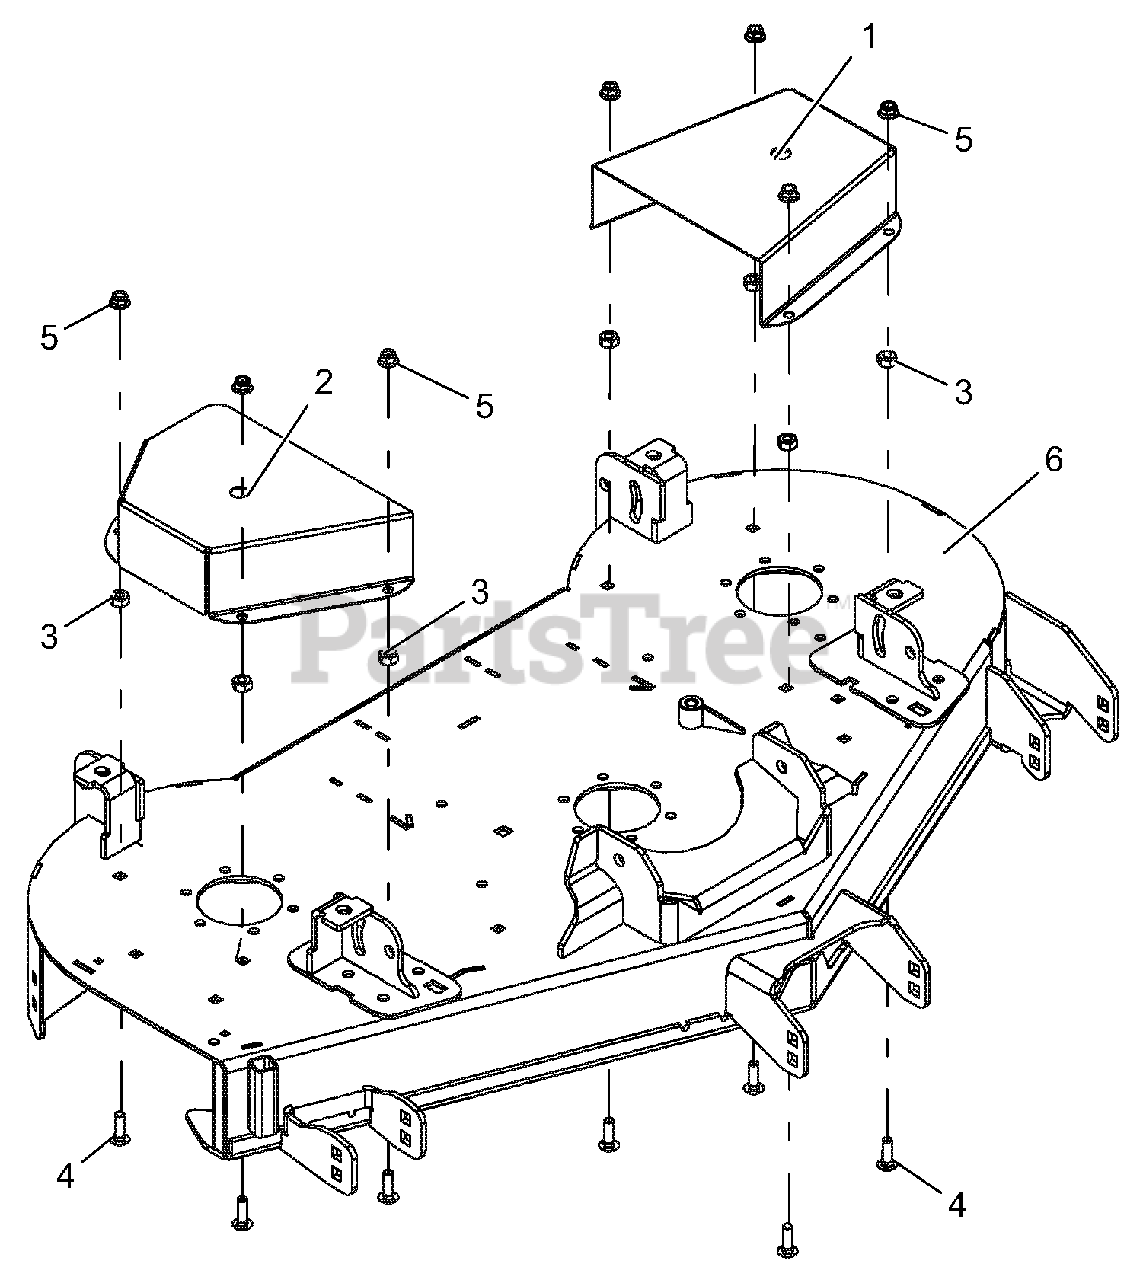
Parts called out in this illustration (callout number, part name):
1	GUARD, 48" LH DECK BELT
2	GUARD, 48" RH DECK BELT
3	NUT-HEAVY HEX .38-16 YWZC
4	BLT-RDHDSQNK .38-16 x 1.25 G5 YWZC
5	NUT-LK-NYL-FLG .38-16 YWZC
6	ASSY, DECK W/DECALS 48" STANCE
